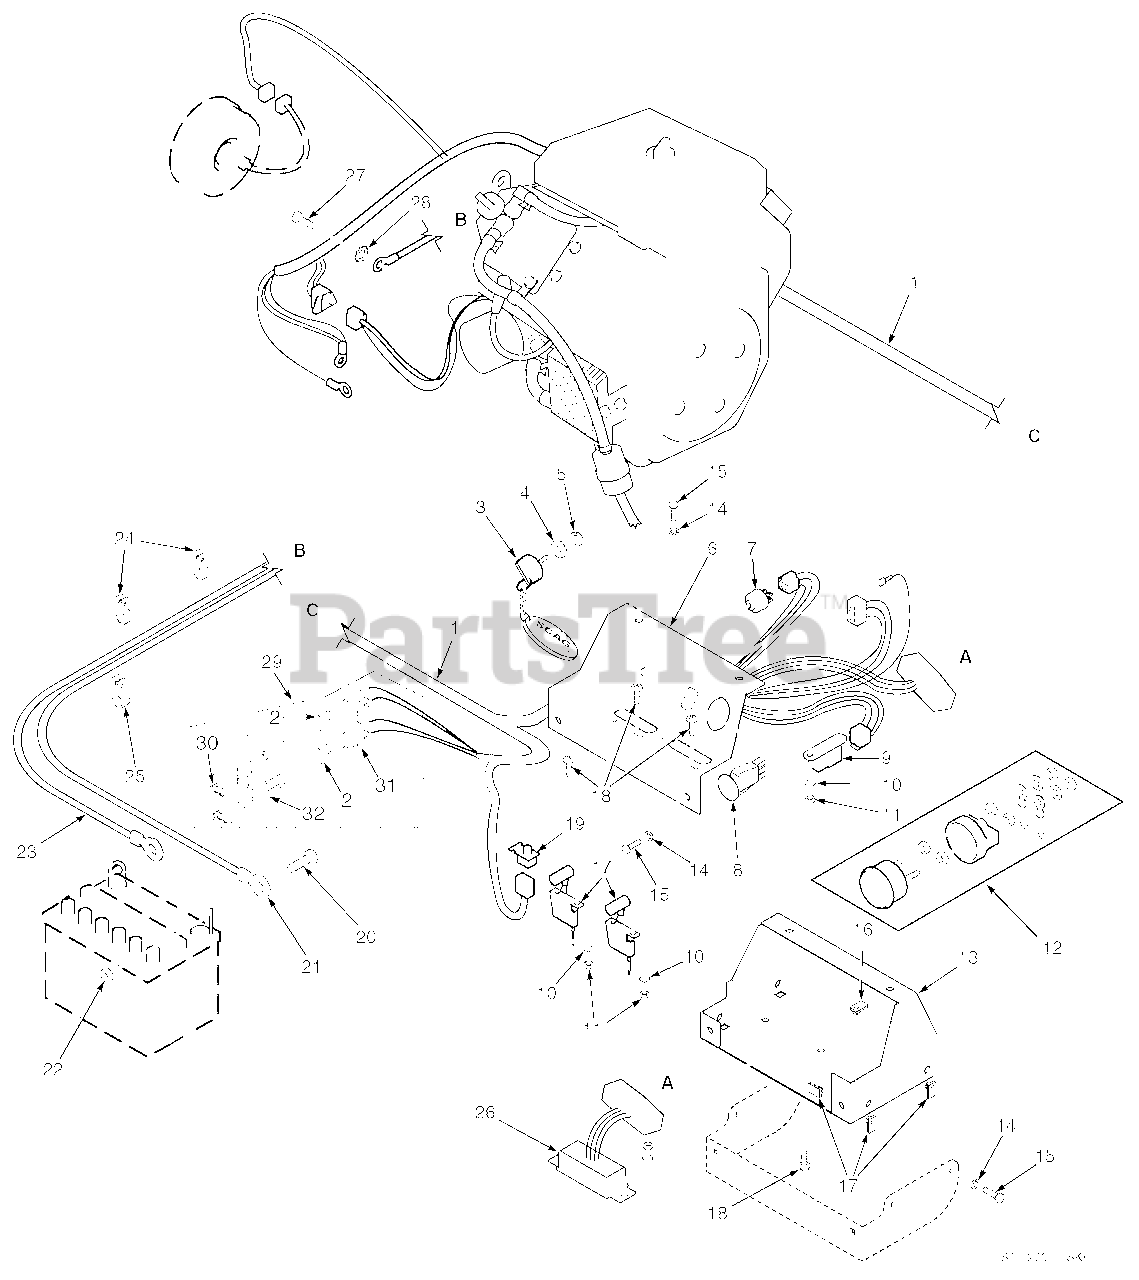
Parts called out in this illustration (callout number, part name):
1	Wire Harness, STT Air-Cooled
2	Fuse, 20 AMP
3	Key, Ignition
4	Nut, Hex 5/8-32
5	Lockwasher, 5/8" Internal
6	Instrument Panel, Top w/Decals
7	Key Switch
8	Switch, PTO
9	Relay
10	Lockwasher, #10 External Tooth
11	Nut, Hex #10-32
12	Ammeter
13	Base, Instrument Panel
14	Lockwasher, 1/4"
15	Bolt, Hex Head 1/4-20 x 3/4"
16	U-Nut, 1/4-20
17	Throttle And Choke Controls
18	Screw, Phillips Washer Head #10-32 x 1/2"
19	Switch, Interlock-Seat
20	Bolt, Hex Head 1/4-20 x 1/2"
21	Cable, Battery - Red
22	Nut, Hex 1/4-20
23	Cable, Battery - Black
24	Clamp, Cable 1/2" ID.
25	Clamp, Cable 3/4" ID.
26	Electronic Module
27	Bolt, Hex Head M8-1.25 x 20mm
28	Lockwasher, 5/16" External Tooth
29	Double Fuse Assembly, Sealed
30	Clip, Wire
31	Fuse Holder
32	Cover, Sealed Double
